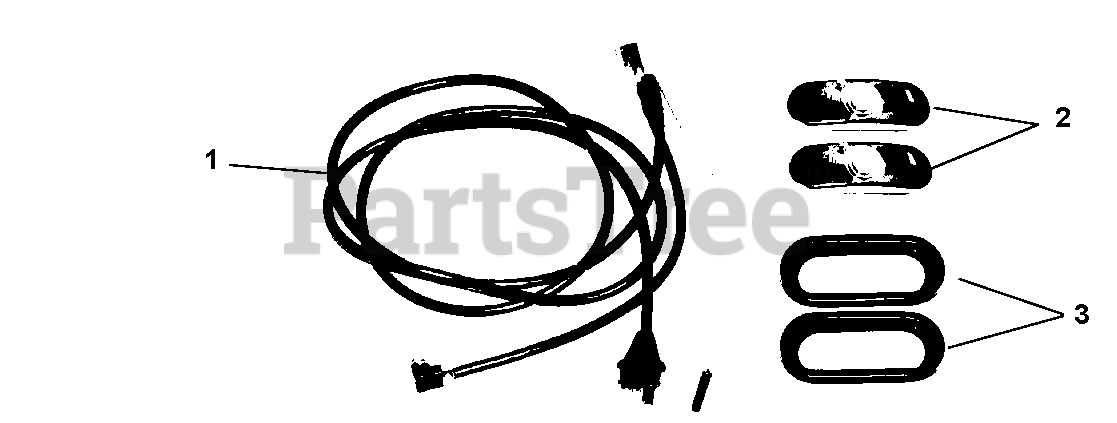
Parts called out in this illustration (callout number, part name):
1	Wiring Harness, Trailer Light Kit
2	Housing, Tail Light With Bulb
3	Grommet, Tail Light Mounting
